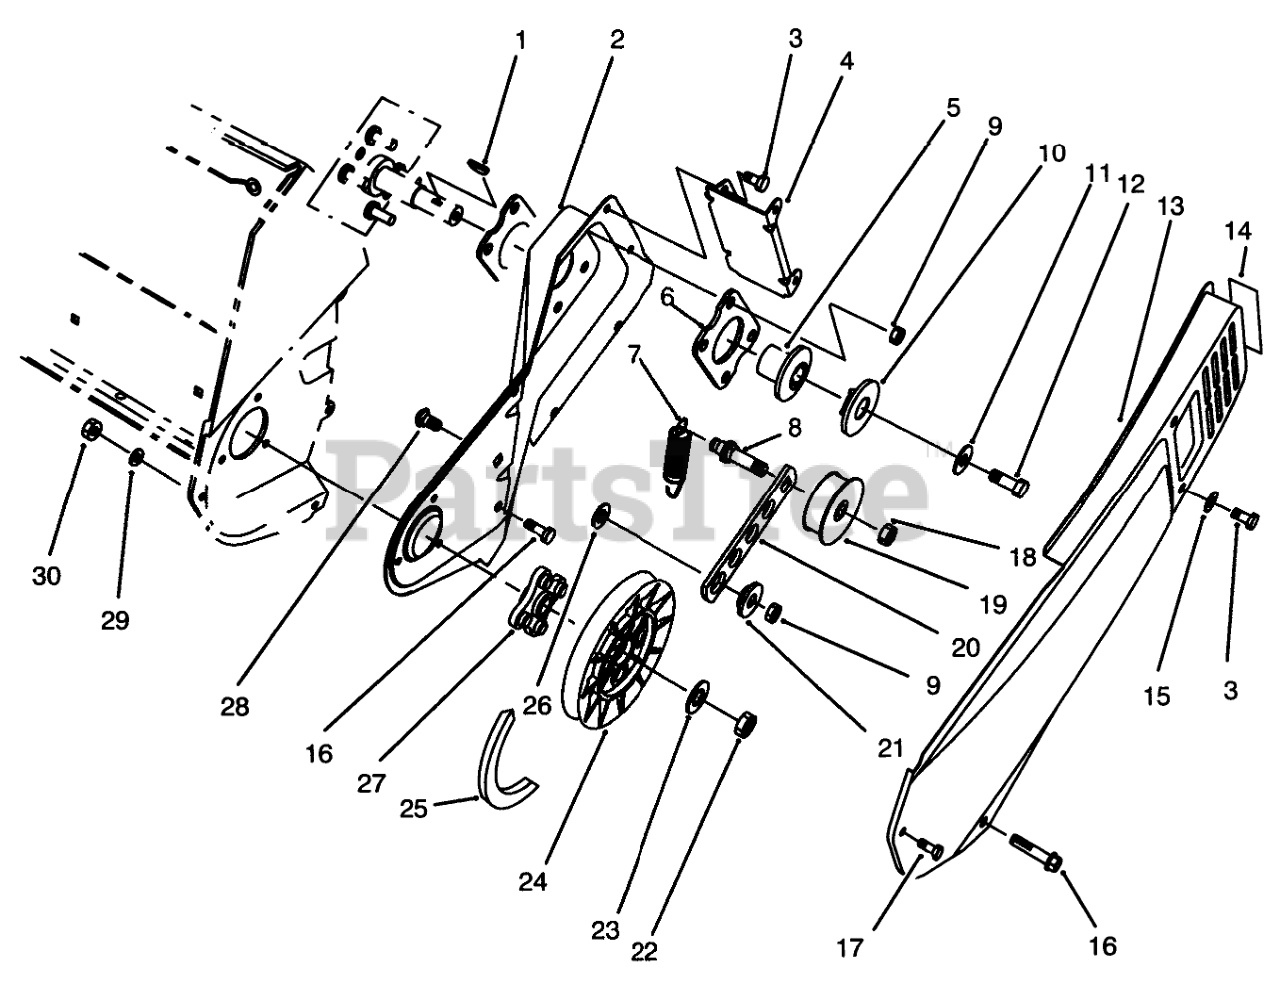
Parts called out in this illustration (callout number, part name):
1	KEY-WOODRUFF
2	Sideplate-LH
3	SCREW-HWH
4	Bracket-Cover
5	Hub-HALF SHEAVE
6	Plate Engine
7	SPRING-EXTENSION
8	PIN-IDLER
9	NUT-LOCK, NI
10	CAP-HALF SHEAVE
11	WASHER-FLAT
12	SCREW-HH
13	Cover-Belt
14	DECAL-HOT
15	WASHER-FLAT
16	SCREW-PLASTIC
18	NUT-LOCK, NI
19	PULLEY-IDLER
20	ARM-IDLER
21	BUSHING-IDLER
22	NUT-LOCK, NI
23	WASHER-FLAT
24	PULLEY-DRIVEN
25	V-BELT
26	WASHER
28	SCREW-CARR
29	WASHER-FLAT
30	NUT-LOCK, NI
